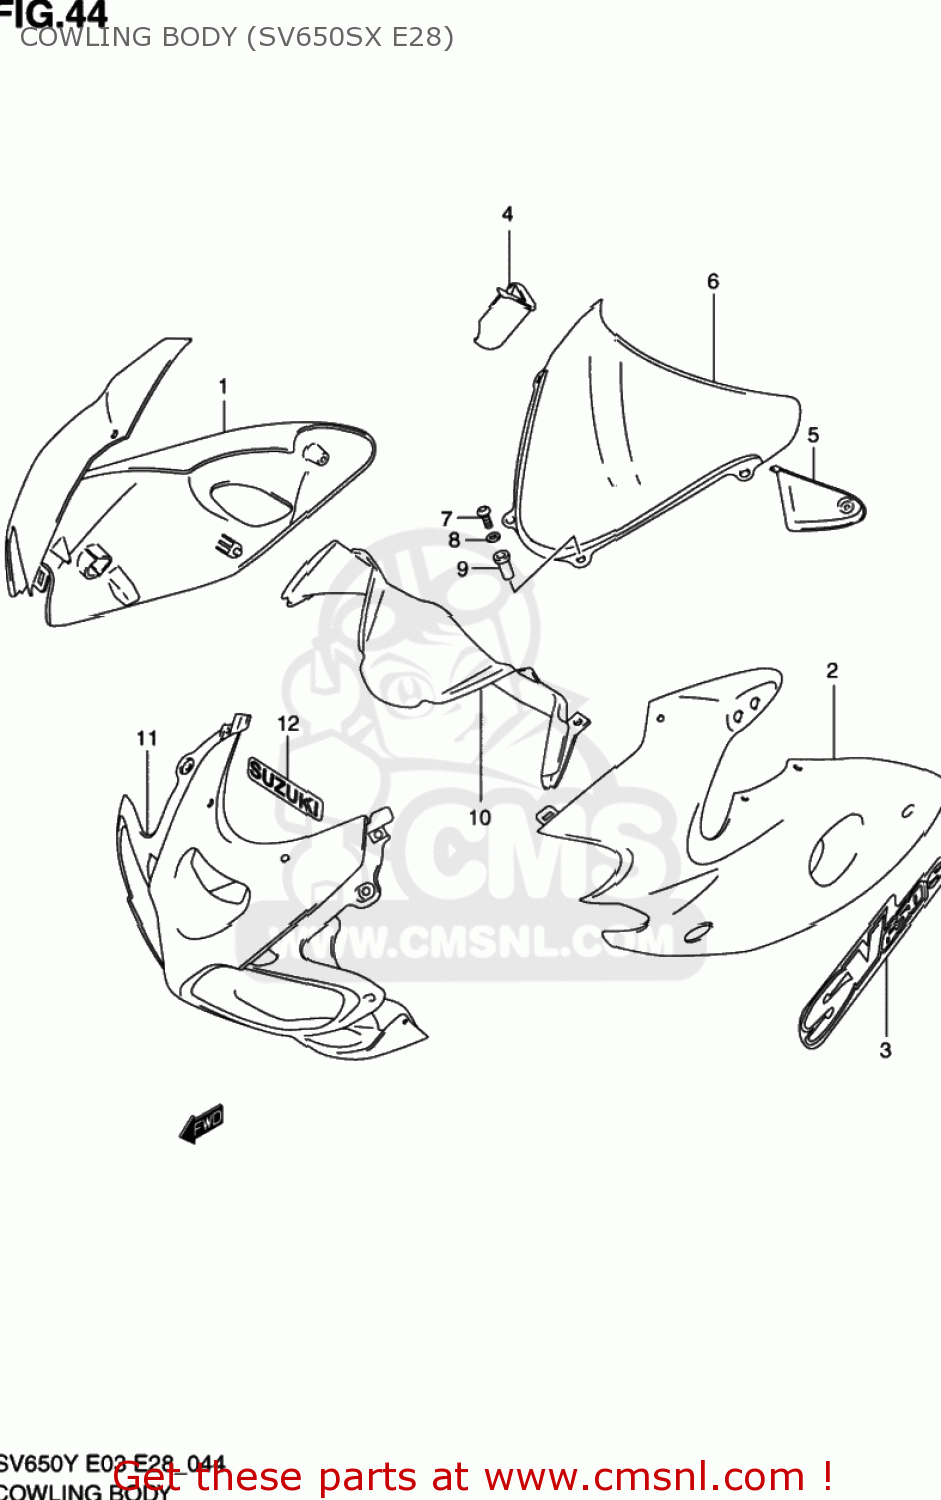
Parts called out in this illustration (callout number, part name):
1	COWLING,SIDE,R
2	COWLING,SIDE,L
3	EMBLEM,COWLING SIDE
4	PANEL,UPR,R
5	PANEL,UPR,L
6	WINDSCREEN
7	SCREW(5X14)
8	WASHER
9	NUT
10	PANEL,METER
11	COWL ASSY,CTR
12	EMBLEM,SUZUKI
